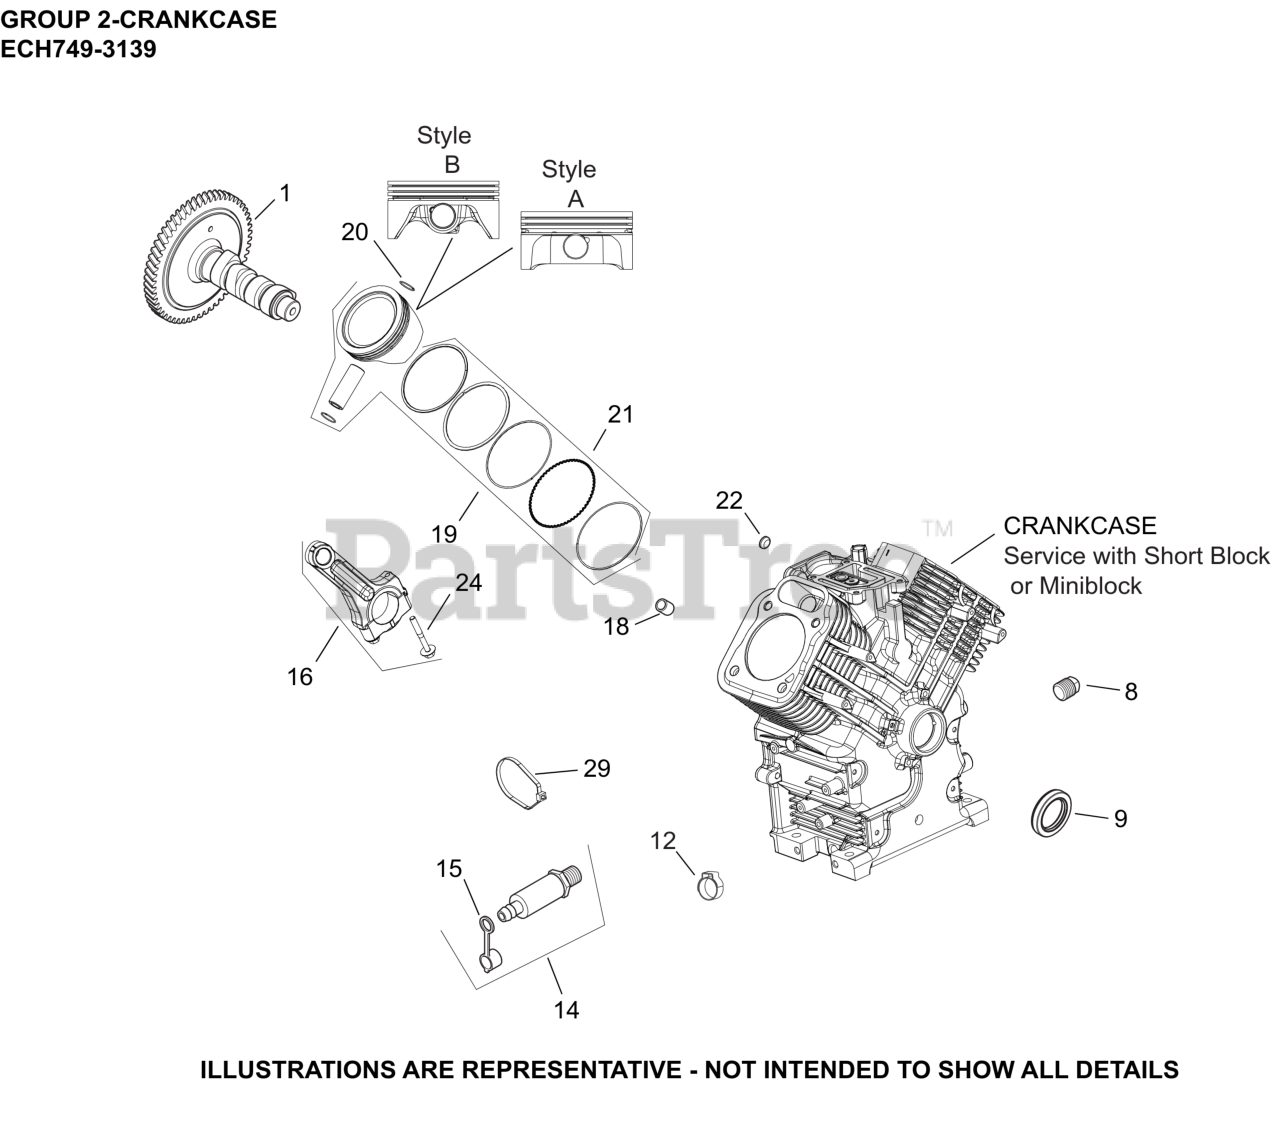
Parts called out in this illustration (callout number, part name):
1	KIT, CAMSHAFT
8	PLUG, HD PIPE 3/8"
9	SEAL, OIL (HELIX LIP)
14	KIT, OIL DRAIN VALVE
15	CAP, OIL DRAIN VALVE
16	ROD, ASSEMBLY CONNECTING
18	PIN, LOCATING
19	KIT,PSTN/RNG STYLE B(STD)
19	KIT,PSTN/RNG STYLE B(.08)
19	KIT,PSTN/RNG STYLE B(.25)
19	KIT,PSTN/RNG STYLE B(.50)
20	RETAINER, PISTON PIN
21	RING SET(STD)STYLE B-1.2mm Tp RING THICK
21	RING SET(.08)STYLE B-1.2mm RING THICK
21	RING SET(.25)STYLE B-1.2mm Tp RING THICK
21	RING SET(.50)STYLE B-1.2mm Tp RING THICK
22	PLUG, CUP
24	KIT, ROD BOLTS-(#25086677S)
